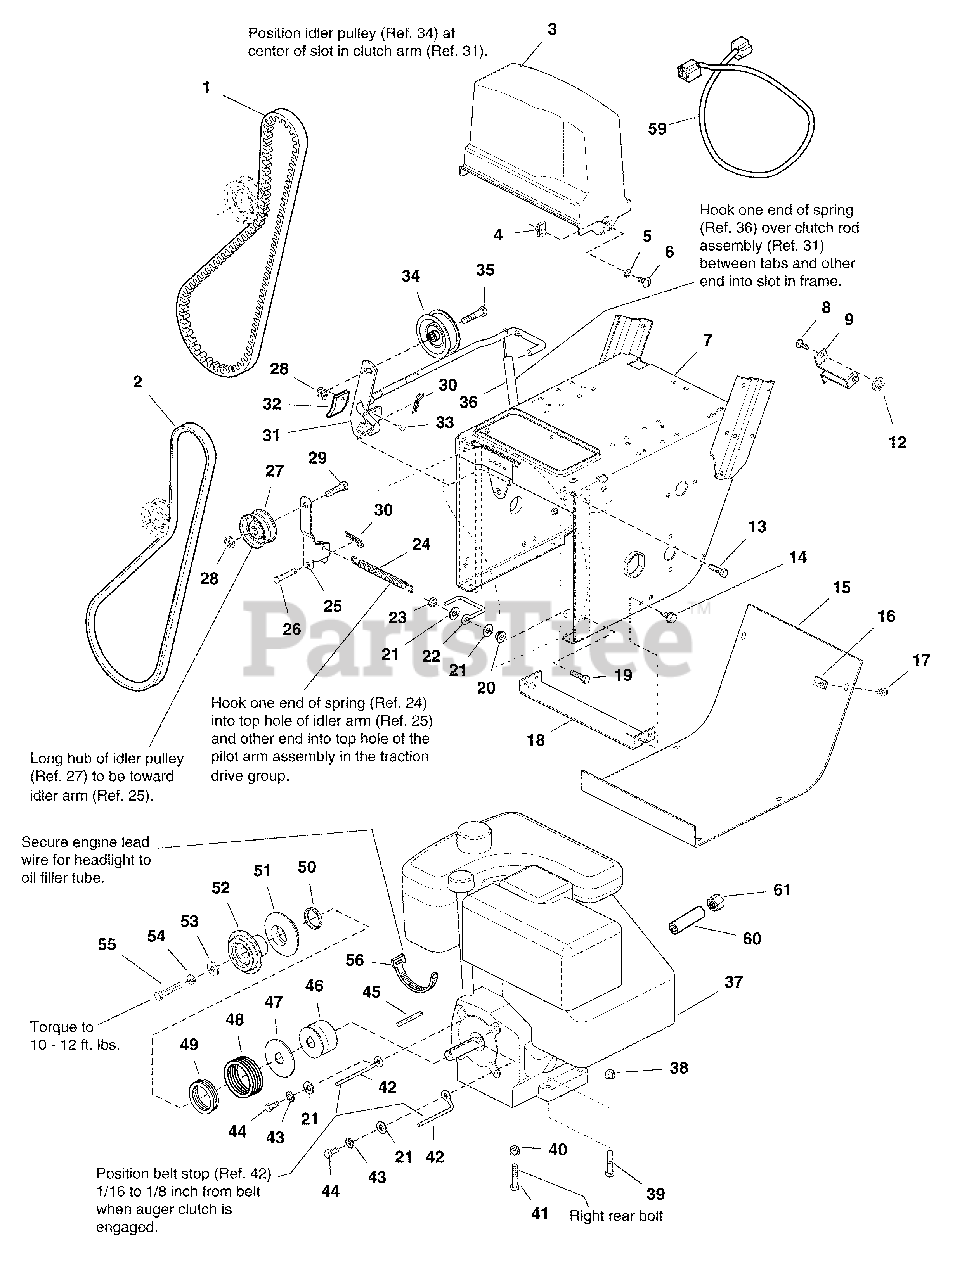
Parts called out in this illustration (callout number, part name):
1	BELT, Traction
2	BELT, Auger Drive
3	GUARD, Belt
4	NUT, Speed, 5/16-18
5	LOCKWASHER, Ext. Tooth, 5/16
6	SCREW, Truss Head, 5/16-18 x 3/4
7	FRAME, Main
8	CARRIAGE BOLT, 1/4-20 x 3/4
9	SUPPORT, Clutch Cable
12	NUT, Hex Washer, 1/4-20
13	CAPSCREW, Hex Head, Whizlock, 5/16-18 x 3/4
14	CAPSCREW, Hex Head, Taptite, 5/16-18 x 3/8
15	COVER, Bottom
16	NUT, Speed, 1/4-20
17	CAPSCREW, Hex Head, Taptite, 1/4-20 x 1/2
18	SUPPORT, Tie Bar
19	CAPSCREW, Hex Head, Whizlock, 5/16-18 x 1-1/4
20	NUT, Hex, Whizlock, 5/16-18
21	WASHER, 11/32 x 3/4
22	GUIDE, Belt
23	NUT, Hex, Centerlock, 5/16-18
24	SPRING, Idler
25	ARM, Idler, Traction
26	PIN
27	PULLEY, Idler
28	NUT, Hex Flang Whiz Lock, 3/8-16
29	CAPSCREW, Hex Head, 3/8-16 x 1-1/2
30	PlN, Hair 5/64 x 1-3/16
31	CLUTCH ROD & BRAKE ASSEMBLY
34	ASSEMBLY, Auger Drive Pulley
35	CAPSCREW, Hex Head, 3/8-16 x 1-3/4
36	SPRING, Extension
38	NUT, Hex, 5/16-18, Black
39	CAPSCREW, Hex Head, 5/16-18 x 2, Black
40	NUT, Hex Flange, 5/16-18
41	CAPSCREW, Hex Head 5/16-18 x 2 G5
42	GUIDE, Belt
43	LOCKWASHER, 5/16
44	CAPSCREW, Hex Head, 5/16-24 x 3/4
45	KEY, Parallel, 3/16 x 13/16 x 7/8
46	PULLEY, Traction
47	WASHER, Thrust
48	SPRING, Compression
49	SPRING, Compression
51	PULLEY, Drive
52	PULLEY, Drive
53	WASHER, 13/32 x 1
54	LOCKWASHER, Spring, 3/8
55	CAPSCREW, Hex Head, 3/8-24 x 2
56	TIE, Self Locking
59	CORD, Electric, 3 Prong (Not a Service Part)
60	PIPE, Oil Drain, 1/4-NPT x 11/16 Long
61	CAP, Hex, 1/4-NPT
